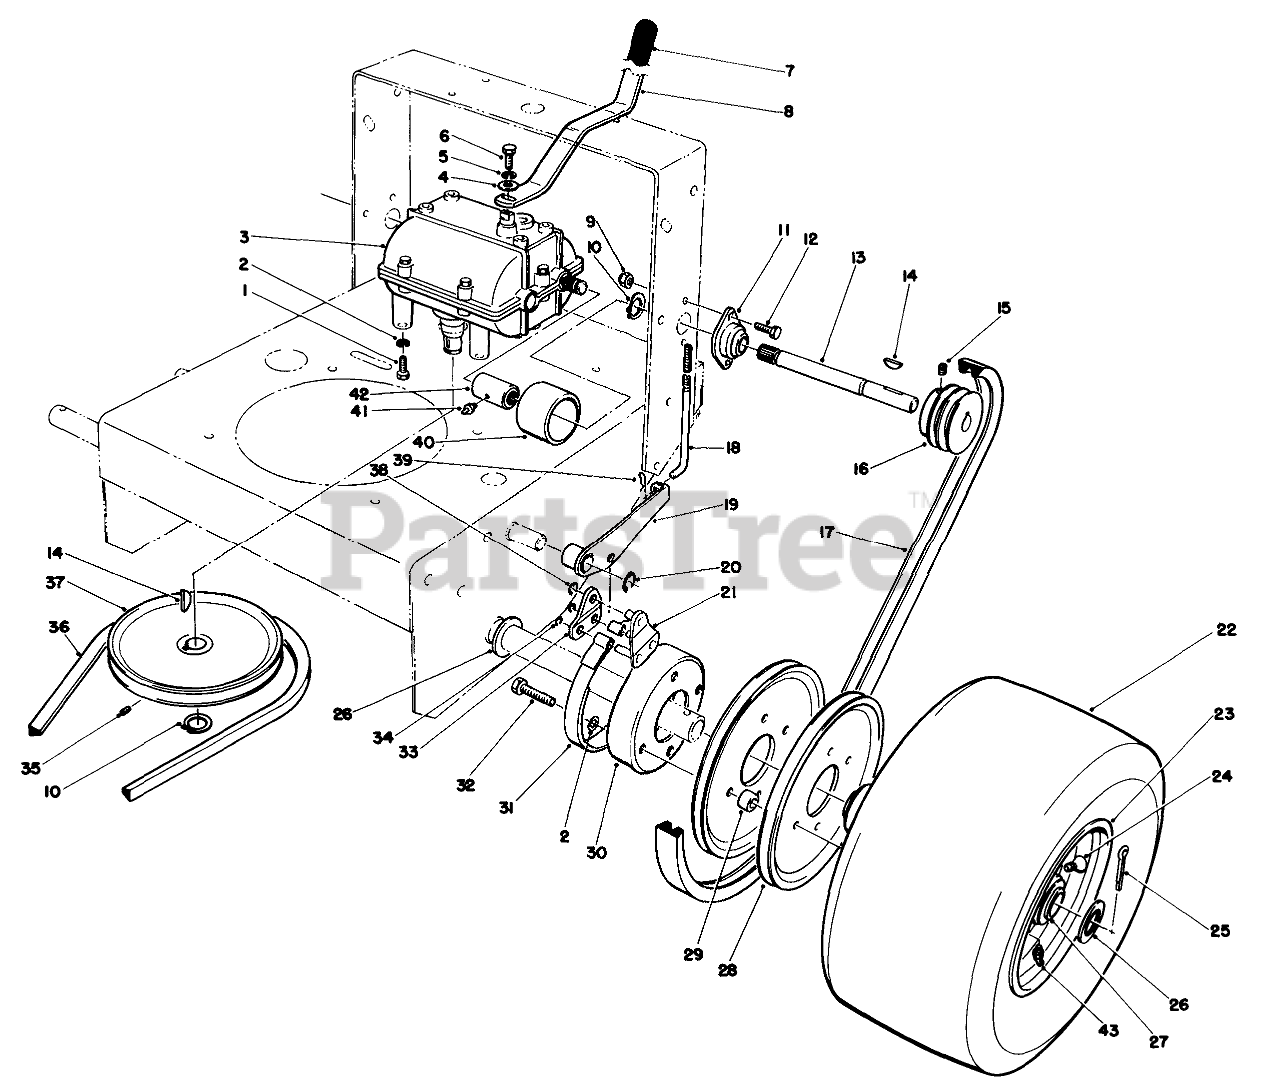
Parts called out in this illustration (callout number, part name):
1	SCREW-HH
2	WASHER-LOCK
3	Transmission
4	SPACER
5	WASHER-LOCK
6	SCREW-HH
8	LEVER-SHIFT
9	NUT-LOCK, NI
10	RING-SNAP, EXTERNAL
11	BEARING-EXTERNAL SHAFT
12	SCREW-HH
13	SHAFT-EXTENSION, RH
14	KEY-WOODRUFF
15	SCREW-SET, HSH
16	Pulley-Drive
17	V-BELT
18	ROD-BRAKE
19	Brake Arm-LH
20	RING-RETAINING
21	LINK-Brake
23	WHEEL AND HUB ASM
24	STEM-VALVE
25	PIN-COTTER
26	WASHER-WHEEL
27	BEARING-BALL, FLANGED
28	Pulley-Wheel
29	SPACER-PULLEY
30	Drum-Brake
31	BAND-BRAKE
32	SCREW-HH
33	Plate-Link
34	RING-RETAINING
35	SCREW-SET
36	V-BELT
37	PULLEY-DRIVEN
38	RING-RETAINING, EXTERNAL
39	PIN-COTTER
40	GUARD-COUPLER
41	FITTING-GREASE
42	COUPLER
43	FITTING-LUBE, 45 DEG
